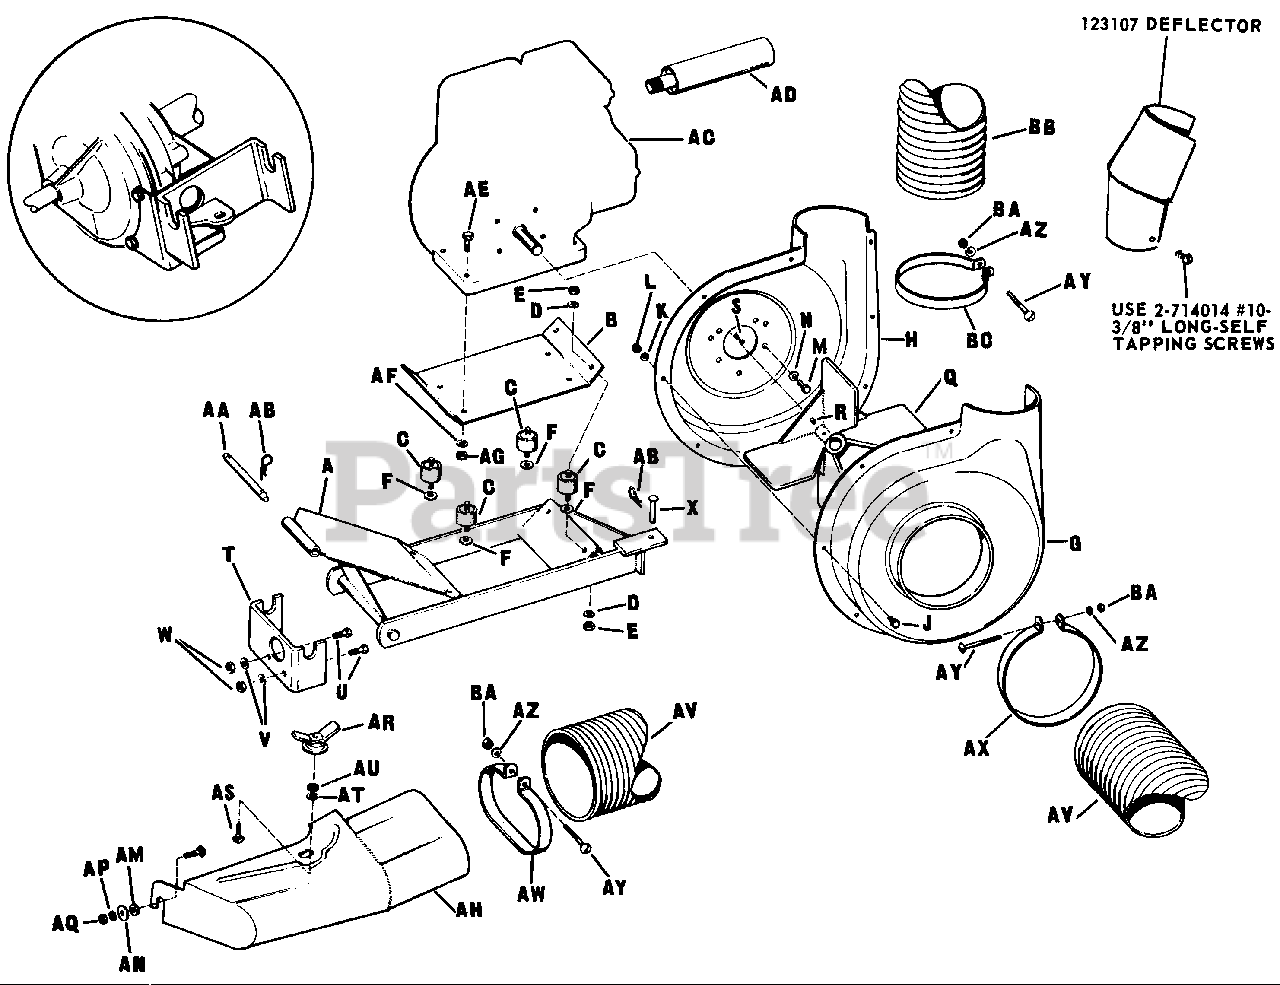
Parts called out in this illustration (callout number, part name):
A	Frame Assembly
B	Engine Plate
C	Connector, Cushion
D	Lock Washer 5/16"
E	Full Hex Nut 5/16"-18 NC
F	Plain Washer 5/16"
G	Housing, Inlet Half
H	Housing Half-Blower, R.H.
J	Hex Cap Screw 1/4"-20 NC x 1/2"
K	Lock Washer 1/4"
L	Full Hex Nut 1/4"-20 NC
M	Hex Cap Screw 5/16"-24 NF x 5/8"
N	Lock Washer 5/16"
Q	Fan Assembly
R	Set Screw 5/16"-18 x 1/2"
S	Key
U	Hex Cap Screw 3/8"-16 x 1-1/2"
V	Lock Washer 3/8"
W	Full Hex Nut 3/8"-16 NC
X	Pin
AA	Counterweight Pin
AB	Clip Spring
AE	Hex Cap Screw 5/16"-18 x 1-1/2"
AF	Lock Washer 5/16"
AG	Full Hex Nut 5/16"-18 NC
AH	Housing Assembly
AL	Carriage Bolt 3/8"-16 x 1-1/4"
AP	Lock Washer 3/8"
AQ	Full Hex Nut 3/8"-16 NC
AR	Nut Assembly
AS	Carriage Bolt 5/16"-18 NC x 1"
AT	Lock Washer 5/16"
AU	Full Hex Nut 5/16"-18 NC
AV	Intake Hose 7" Diameter
AW	Hose Clamp
AX	Hose Clamp
AY	Hd. Rd. Mach. Screw 1/4"-20 x 3"
AZ	Lock Washer 1/4"
BA	Full Hex Nut 1/4"-20 NC
BB	Exhause Hose 6" Diameter
BC	Hose Clamp
